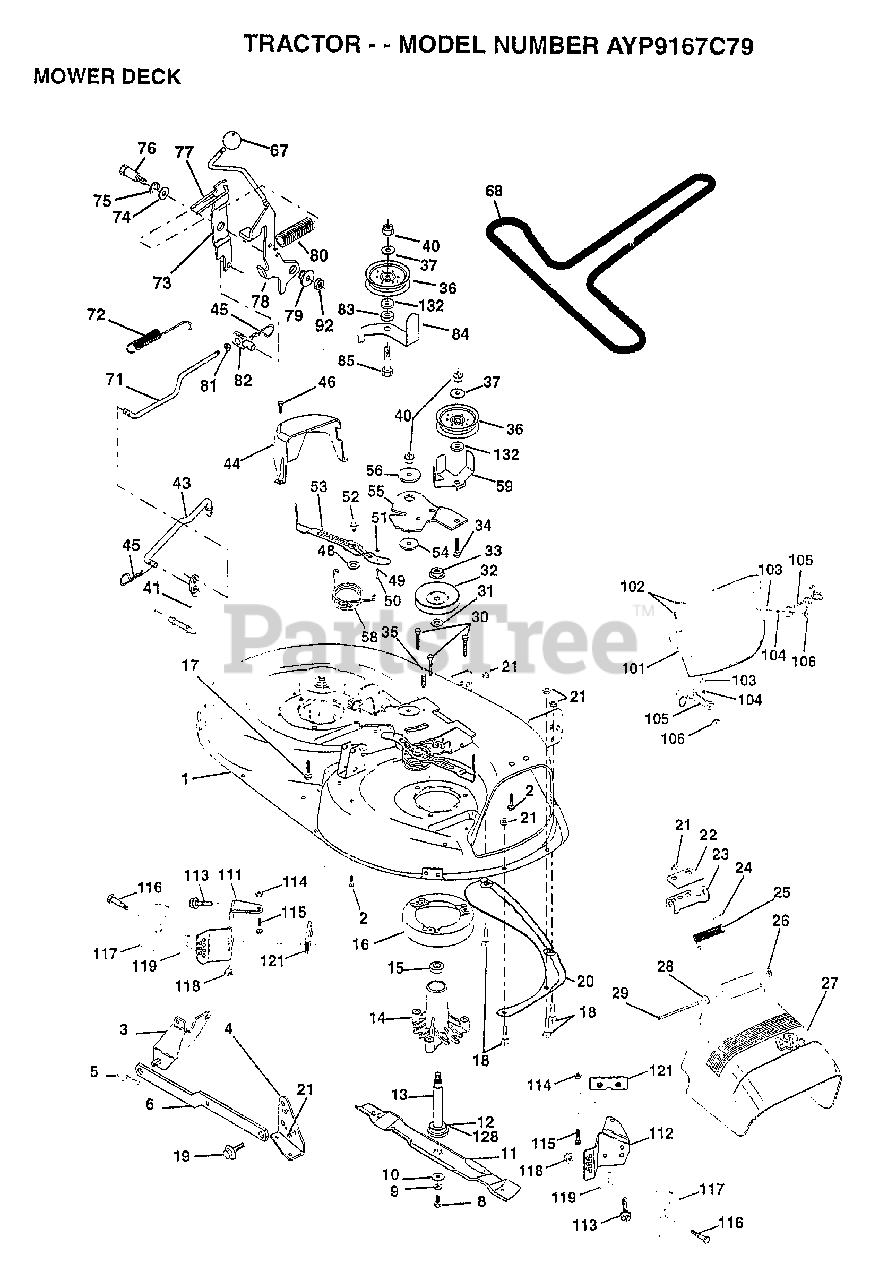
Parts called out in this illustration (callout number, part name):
1	DECK.WELD.42.
2	BOLT
3	BRKT ASM SWAY BAR
4	BRKT DECK SW BAR
8	BLADE BOLT
10	WASHER.HARD.BLADE
11	"BLADE.42"" MULCHER"
12	BEARING.BALL
14	HSG ASM MANDREL
15	BEARING
16	STRIPPER RND MWR
17	BOLT RDHD 3/8-16
18	BOLT
19	BOLT SHD 5/16-18
22	STIFFENER BRKT
23	DEFLECTOR BRKT
24	CAP-SLEEVE LT
25	SPRING TORSION
26	NUT PUSH M
27	DEFLECTOR.SHIELD
28	WASHER
29	HINGE ROD
30	"SCREW-THD ROLL,WA"
31	WASHER
32	PULLEY.MANDREL.42
34	BOLT
35	XMAS TREE FASTNER
36	FLAT IDLER PULLEY
37	WASHER
41	PIVOT ROD
43	ROD CLUTCH W/NIBS
44	GUARD MAND LH BLK
45	RETAINER M
46	SCREW.1/4-20X5/8
48	HARD SMALL WASHER
49	ROLLER ASM-CAM
50	SHOULDER BOLT
51	LOCKNUT
52	BOLT.SHLD.5/16-18
54	HARDENED WASHER
55	ARM-IDLER
56	SPACER RETAINER
58	SPRING TORSN BRAK
59	GUARD IDLER TUV
67	KNOB T(3/8 HOLE)
68	BELT.V.T-PATH
71	ROD CLUTCH 38/42
72	RETURN SPRING
73	CLUTCH ARM SECOND
74	WASHER
75	RING
76	SHOULDER BOLT
77	SPRING KEEPER
78	LEVER ASM-CLUTCH
79	BUSHING
80	SPRING.CLUTCH.MWR
81	TRUNION ADJ
82	NUT
83	WASHER
84	"KEEPER-BELT,FIXED"
85	BOLT RDHD 3/8-16
92	NUT
101	"COVER.MULCH.42"""
102	SCREW
103	WASHER #10
104	LOCKWASHER
106	WELDNUT
111	BRACKET.GWHL.LH.
112	BRACKET.GWHL.RH.
113	SCREW
116	BOLT.SHOULDER
117	WHEEL GAGE DONUT
118	LOCKNUT
119	WASHER
121	BRACKET.EXTRD.GWL
128	WASHER.FELT.
132	WASHER GT
